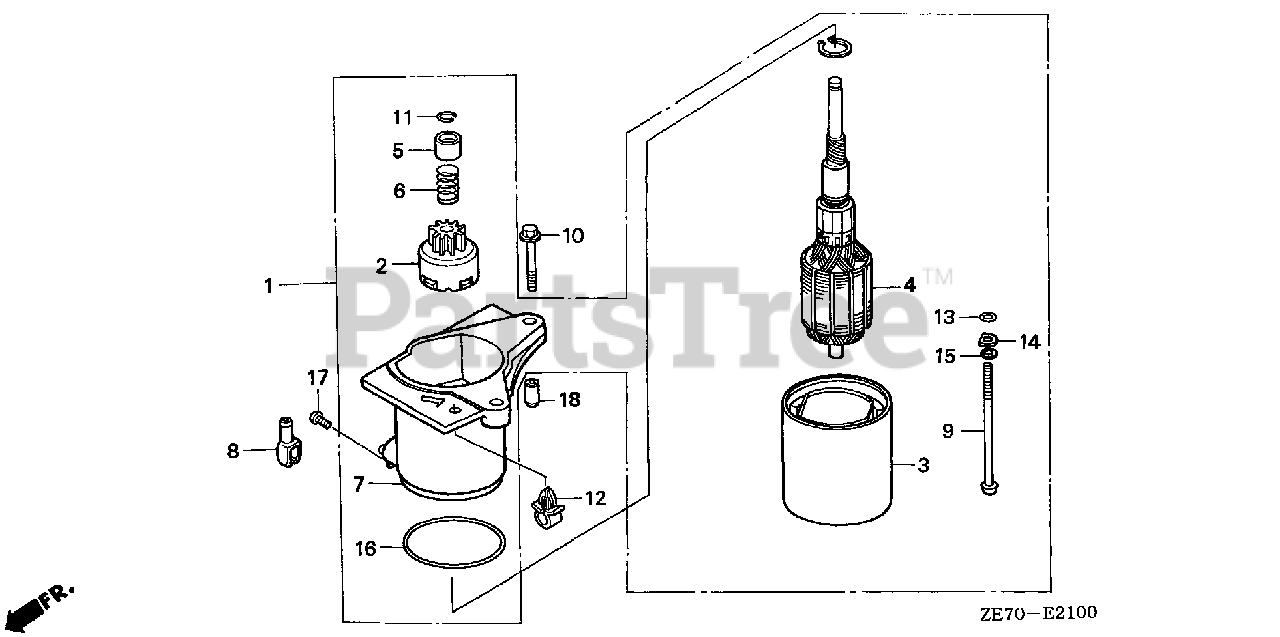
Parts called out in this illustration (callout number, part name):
1	STARTER MOTOR UNIT
2	GEAR ASSY., PINION
3	YOKE ASSY.
4	ROTOR ASSY.
5	PIECE, STOPPER
6	SPRING, RETURN
7	BRACKET, FR.
8	COVER, TERMINAL
9	BOLT, SETTING
10	BOLT, FLANGE (6X32)
11	CIRCLIP, OUTER (8.3MM)
14	WASHER, SPECIAL
15	WASHER, SPRING
18	PIN, DOWEL (8X14)
